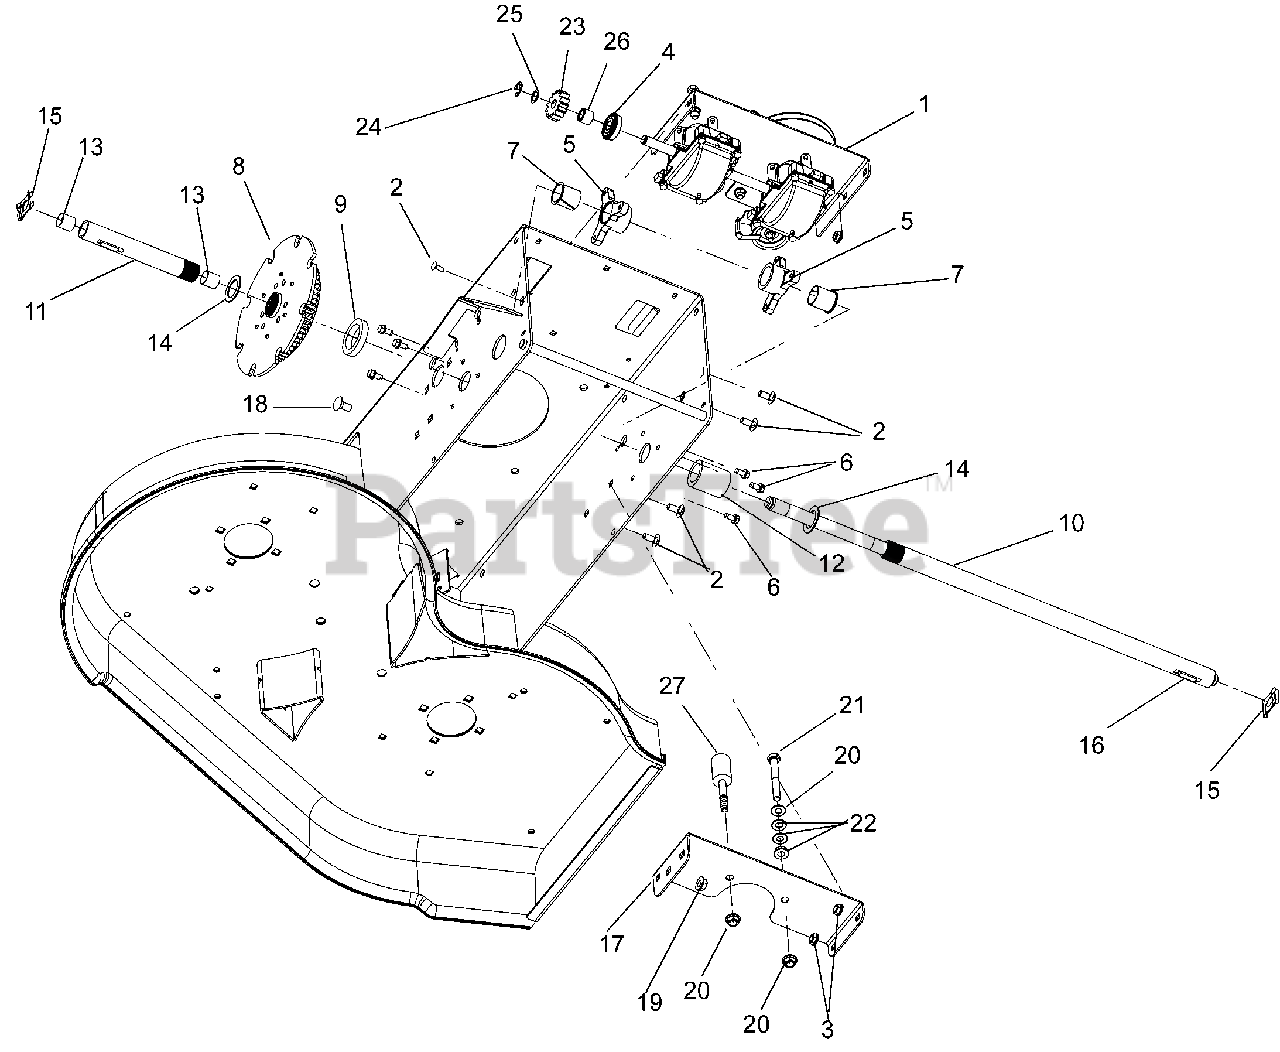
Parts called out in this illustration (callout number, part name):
1	Kit, WAW Transmission
2	Bolt, Round Head, Square Neck .31-18 x .75
3	Nut, Locking Top Flange .31-18
4	Bearing, Sealed Ball .50 1.38 x .438
5	Bushing, Rake Shaft 1"
6	Screw, Tapping Hex Washer Head .25-20 x .50
7	Bushing, Flange Split 1.0"
8	Kit, Differential
9	Washer, Flat Nylon 1.42 x 2.03 x .35
10	Shaft, Axle Long
11	Shaft, Axle Short
12	Spacer 1.0 x 1.5 x 1.57
13	Bushing, Sleeve .706 x .764 x .75
14	Washer, Flat Steel 1.0 x 1.50 x .062
15	Clip, Snap .625 Diameter
16	Key, Rectifier .25 x .188 x 1.00
17	Bracket, Belt Finger Mounting
18	Bolt, Round Head Square Neck .38-16 x .75 (SN 000101 – 000609)
19	Nut, Locking Top Flange .38-16 (SN 000101 – 000609)
20	Nut, Flange .375-16
21	Bolt, Hex .38-16 x 3.00
22	Washer, Flat Steel .406 x 1.50 x .245
23	Pinion, Transmission Drive
24	Ring, External Retaining .500 x .042
25	Washer, Thrust .500 x .020
26	Retainer, Bearing
27	Belt Finger
